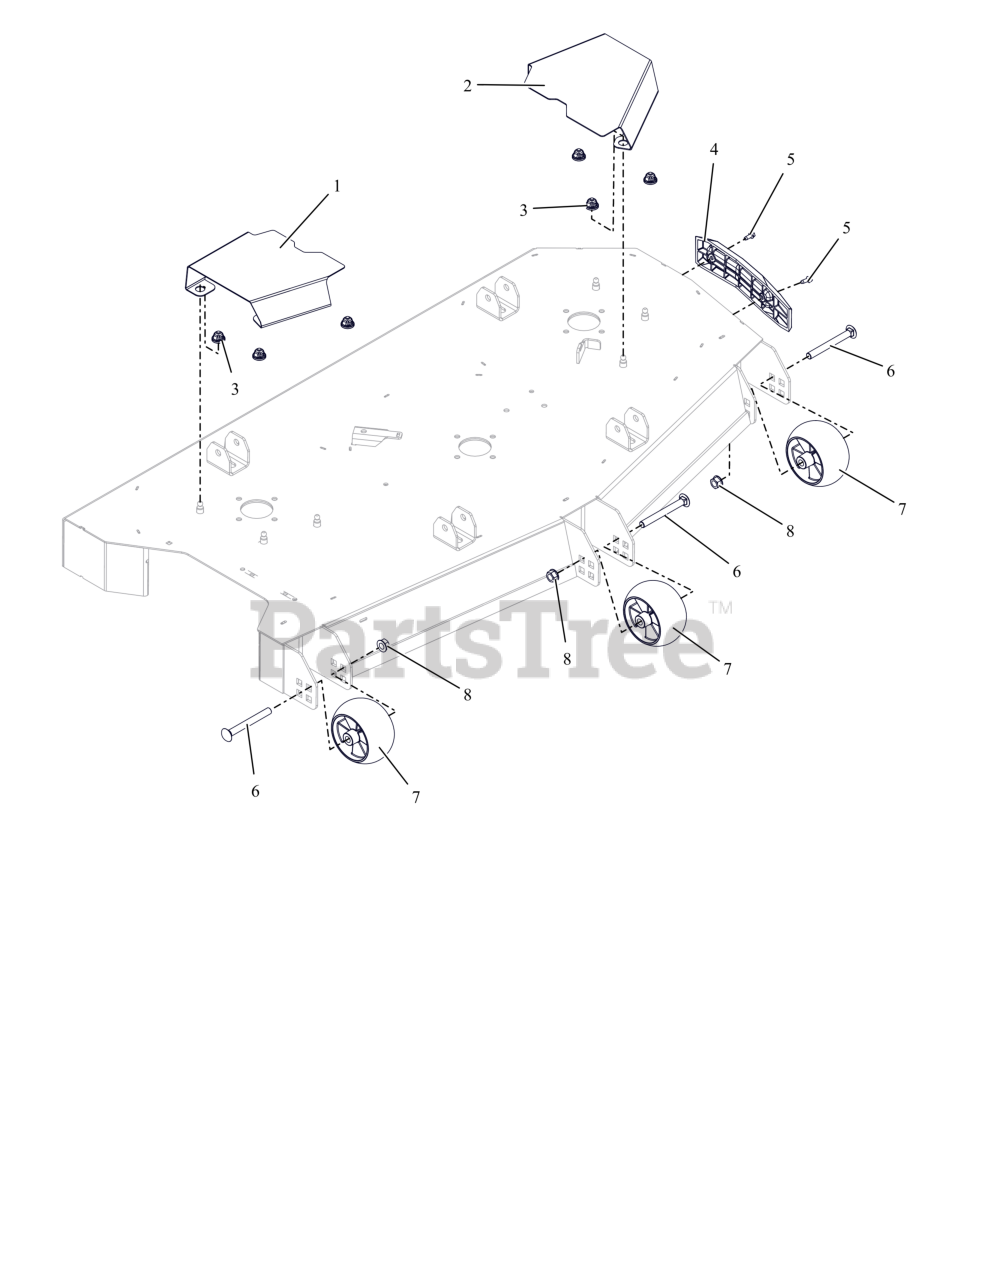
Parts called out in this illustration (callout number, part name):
1	COVER- RIGHT BELT
2	COVER- LEFT BELT
3	GROMMET, 10MM BOLLHOFF
4	BUMPER- DECK
5	SCR,TAP .25-20X.625 HWH ZCC
6	BLT,RHNS .50-13X4.50 G5 ZCC NS
7	WHEEL, ANTI SCALP - 5X3 CTR W/RIBS
8	NUT-LK-CTR-FLG .500-13 GG ZCC
